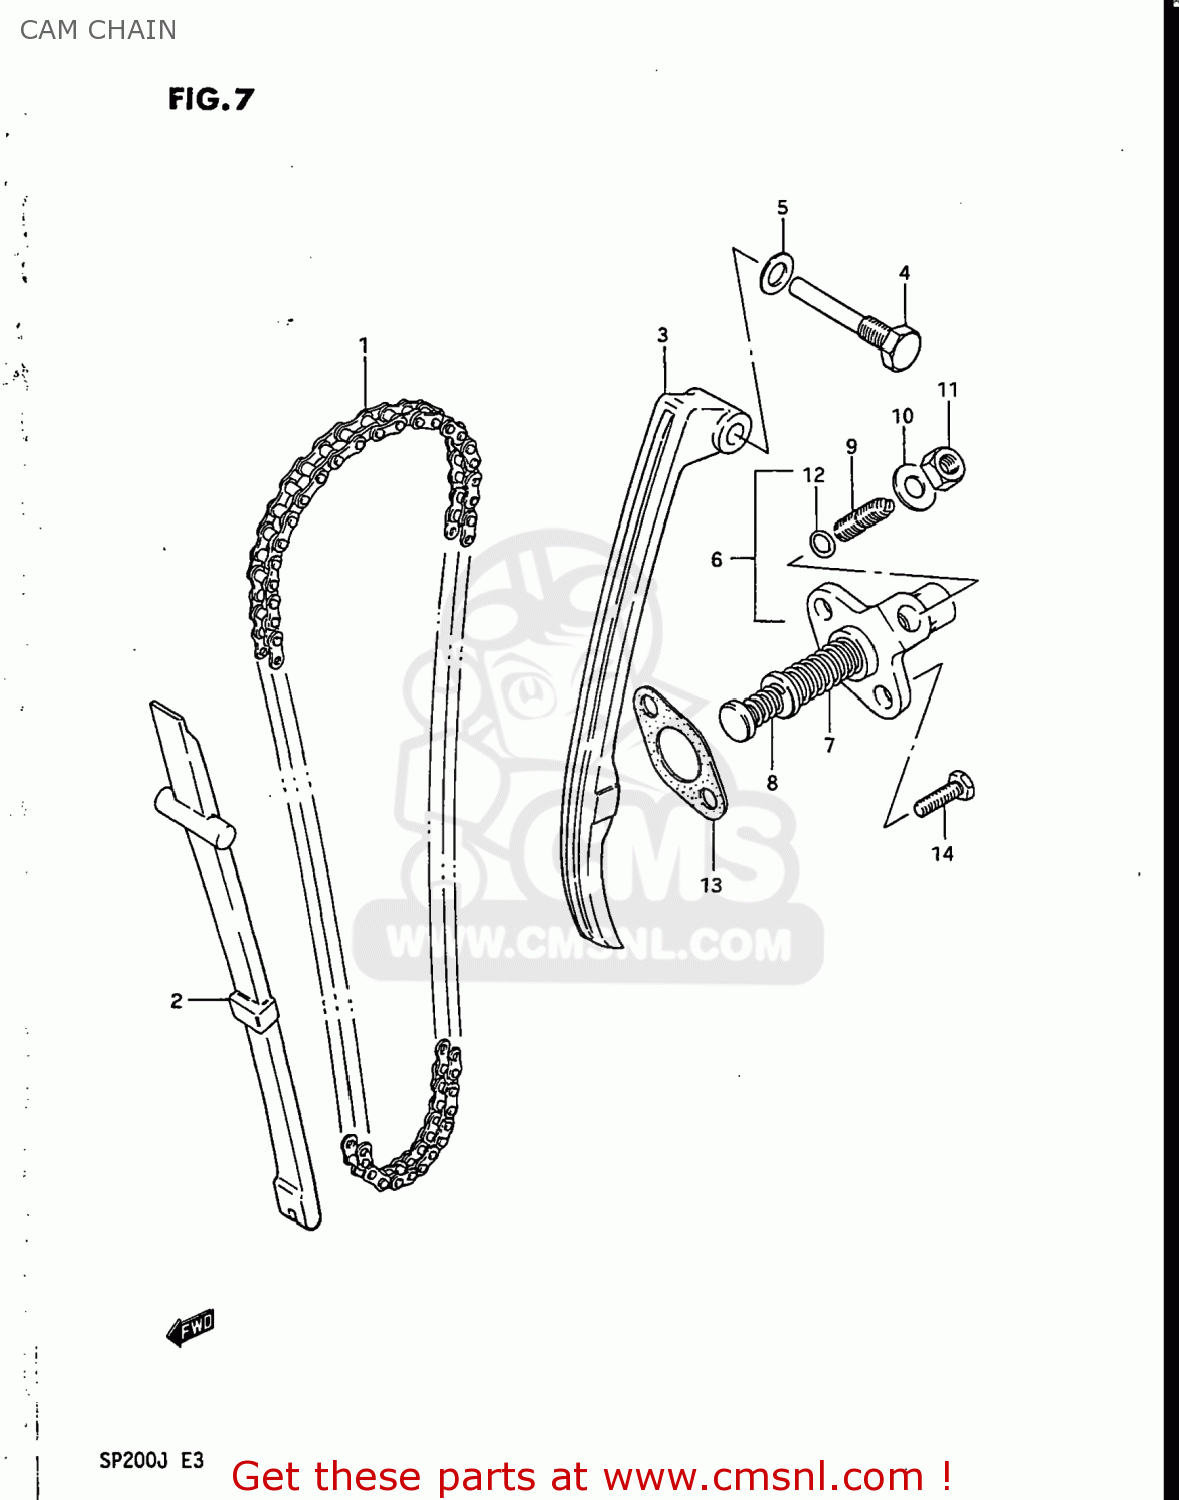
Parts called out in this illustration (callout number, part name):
1	CHAIN,CAMSHAFT DRIVE 102L
2	GUIDE,CAM CHAIN
3	TENSIONER,CAM CHAIN
4	BOLT,CAM CHAIN TENSIONER
5	GASKET 8.2X14X1 (NAS)
6	ADJUSTER ASSEMBLY,TENSIONER
7	SPRING
8	SPRING
9	SCREW
10	WASHER
11	NUT
12	O RING(D:1.9,ID:5.7)
13	GASKET,TENSIONER ADJUSTER (NAS)
14	BOLT
